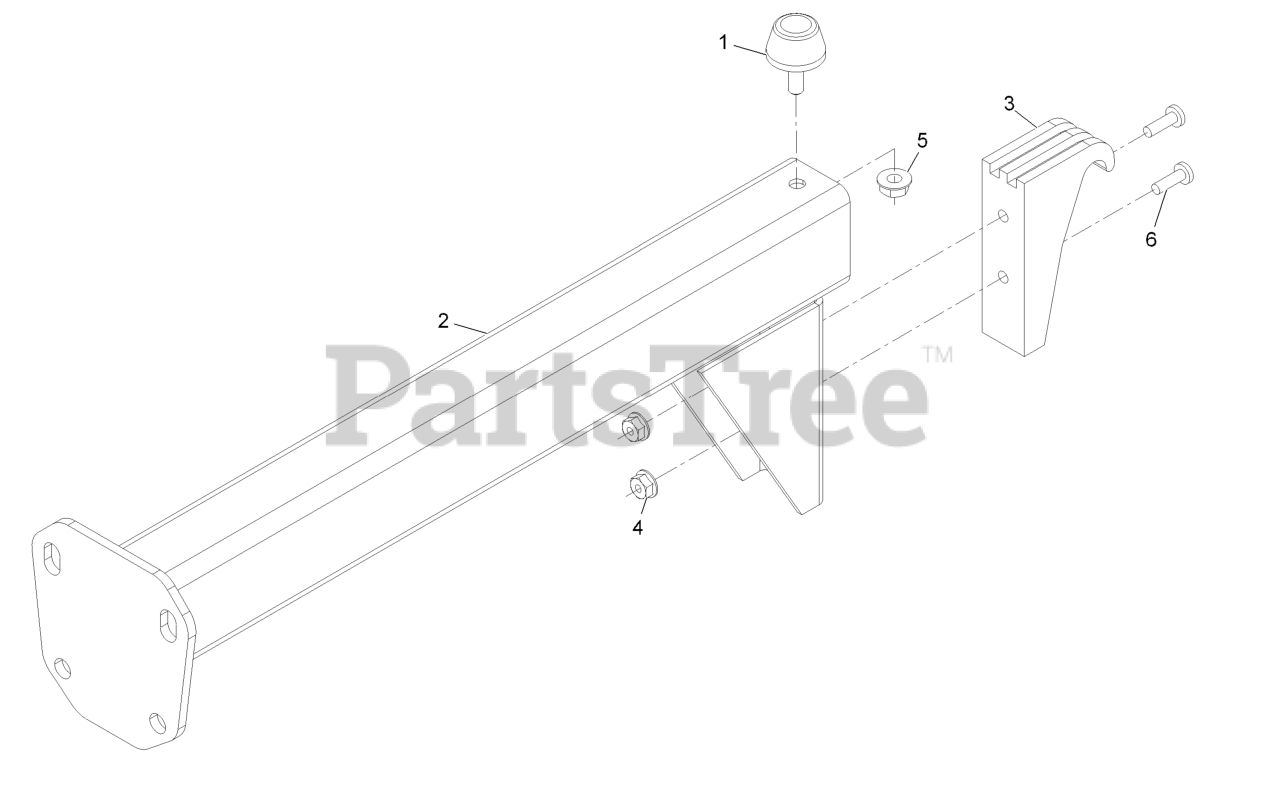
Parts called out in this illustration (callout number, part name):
2	Support-Bag
4	Nut-Whizlock #10-24
5	Nut-Whizlock 1/4-20
6	Screw-PPH #10-24 X 5/8
